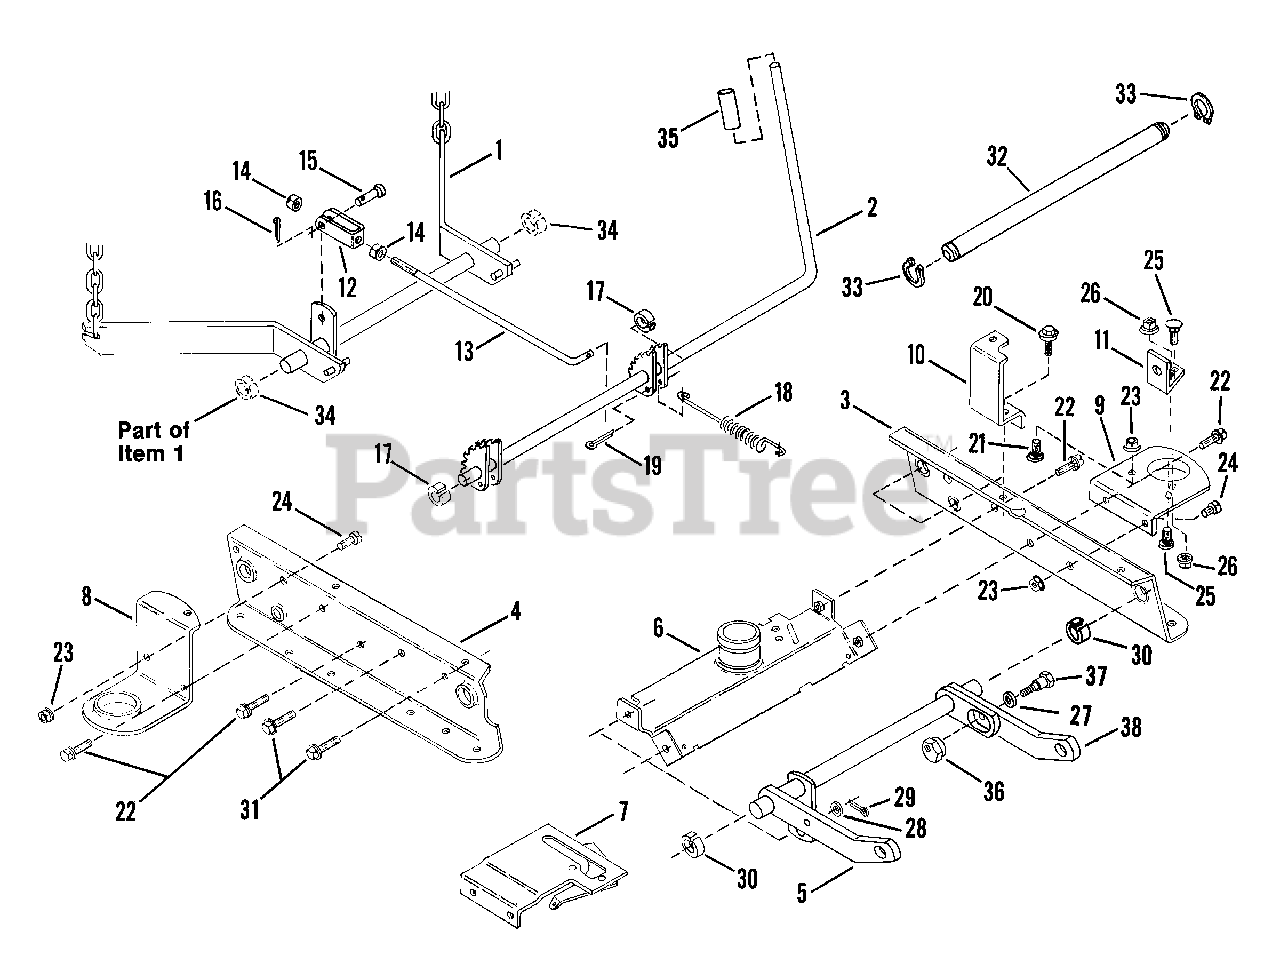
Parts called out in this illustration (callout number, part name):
1	ASSEMBLY, Rear Lift Arm
2	LIFT LEVER STRUCTURE
3	RAIL, Left Half
4	RAIL, Right Half
5	STRUCTURE, Front Lift Arm
6	BRACE, Weldment
7	ASSEMBLY, Clutch Plate
8	SPINDLE, Brace Right Half
9	SPINDLE, Brace Left Half
10	BRACKET, Cover
11	ANCHOR
12	CLEVIS, Timing Rod
13	ROD, Timing
14	NUT, Hex 3/8-24
15	PIN, 3/8 x 1 1/16" Clevis
16	PIN, Cotter 3/32x3/4
17	RING, White
18	SPRING, (CAM-LIFT)
19	PIN, Cotter 5/32x1
20	SCREW, Self-Tapping 1/4-20x5/8
21	SCREW, Cap-Hex Head 3/8-24x1
22	SCREW, Hex Washer Self Tapping 3/8-16x1
23	NUT, Lock 3/8-24
24	SCREW, Cap-Hex Head 3/8-24x3/4
25	BOLT, Carriage 5/16-18x3/4
26	NUT, Hex Flange Lock 5/16x18
27	WASHER, 3/8 Internal Lock
28	WASHER, 3/8
29	PIN, Cotter 1/8x3/4
30	RING, Red
31	SCREW, Hex Washer Self Tapping 5/16-18x5/8
32	SUPPORT, Rod
33	RING, 5/8" External Retaining
34	RING, Blue
35	GRIP, Height Adjustment Lever
36	ECCENTRIC, Leveling
37	BOLT, Shoulder
38	ARM, Front Lift-Left
